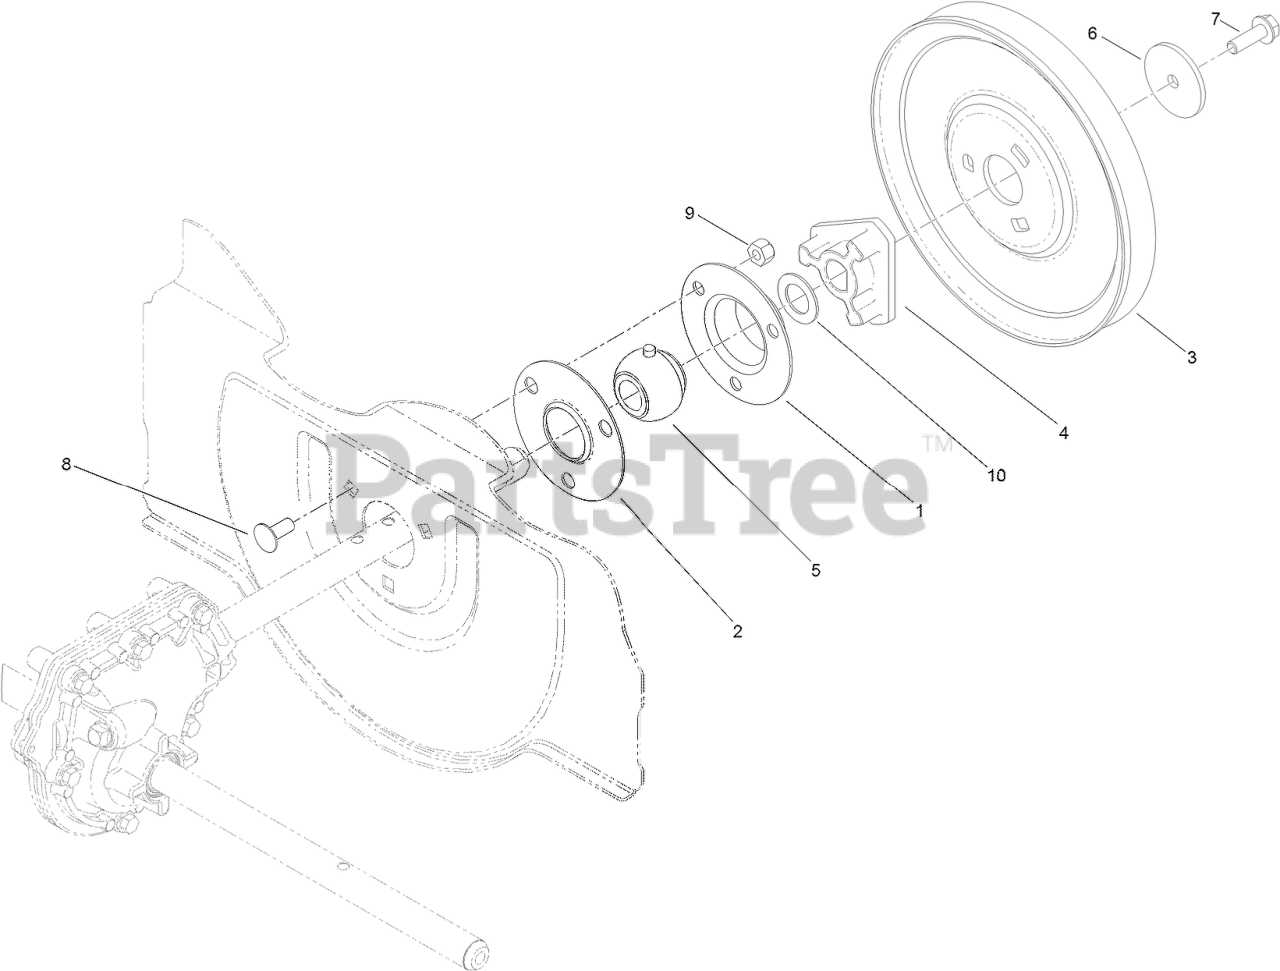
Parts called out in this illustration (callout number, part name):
1	FLANGE-CUP, BEARING
2	FLANGE-CUP, BEARING
3	PULLEY-IMPELLER
4	HUB-IMPELLER, PULLEY
5	BEARING
6	WASHER-PLAIN
7	SCREW-HHF
8	SCREW-CARR
9	NUT-LOCK, NI
10	WASHER-THRUST
